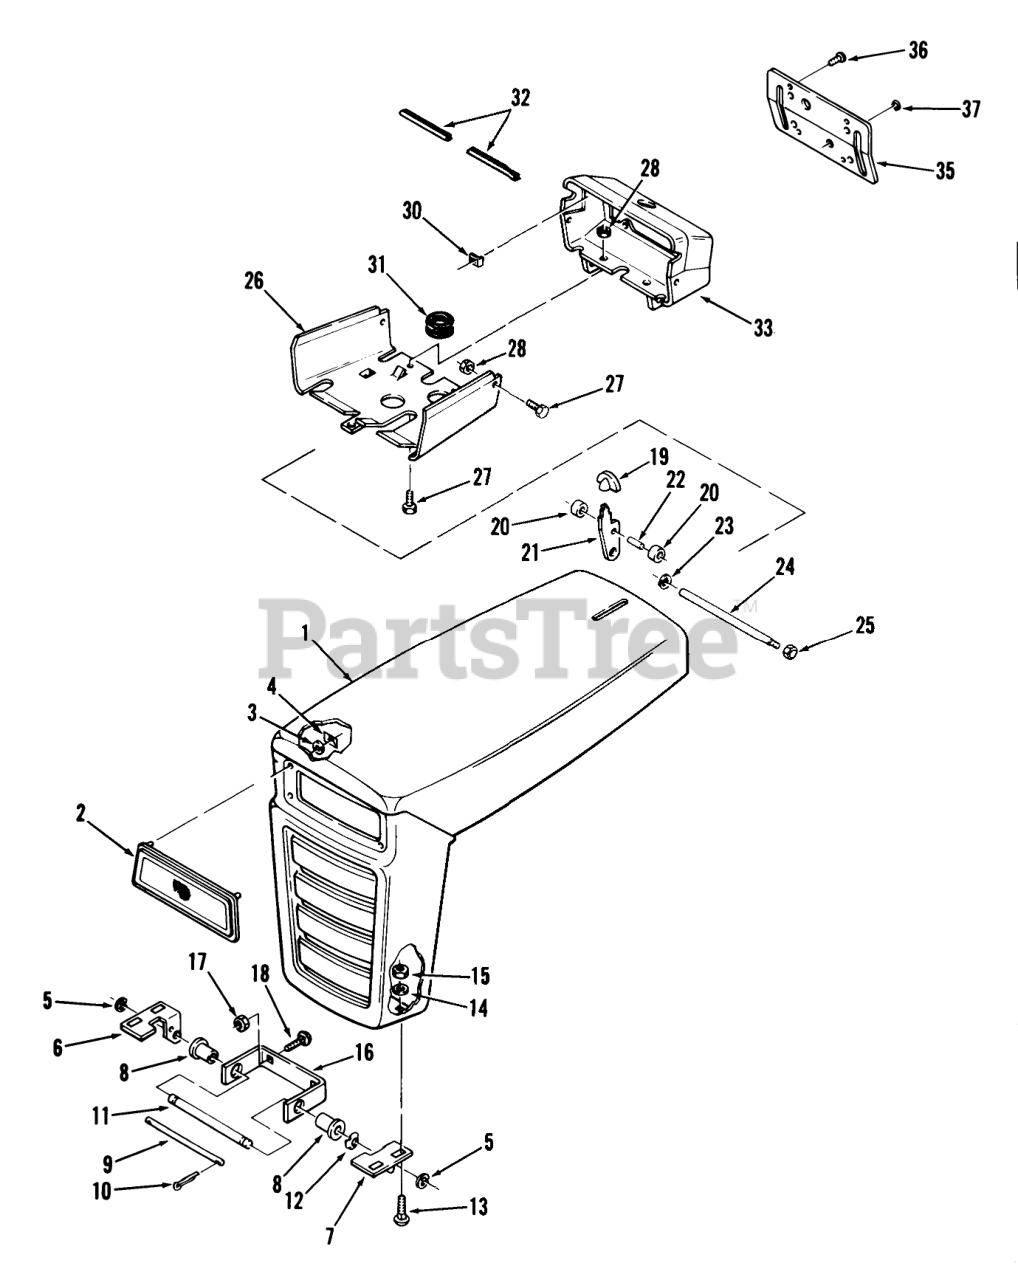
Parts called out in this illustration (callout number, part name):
1	Hood
2	ESCUTCHEON PLATE
3	WASHER
4	SPEED NUT
5	RING-RETAINING
6	BRKT-GRILL PIVOT RH
7	BRKT-GRILL PIVOT LH
8	BUSHING-NYLINER
9	ROD PIVOT STOP
10	Cotter Pin
11	Rod-Pivot
12	WASHER-SPRING
13	Bolt
14	WASHER 5/16 SAE
15	Nut
16	Bracket-Hood Pivot
17	Nut
18	Bolt-Carriage
19	KNOB
20	Roller
21	LEVER HOOD LATCH
22	SPIROL PIN
23	SPEED NUT
24	Rod Latch
26	Support-Tank
27	Screw
28	Nut
30	SPEED NUT
31	Grommet
32	EDGE TRIM 4IN OF 102896
33	Housing
35	Control Panel
36	SCREW BLACK
37	PLUG BUTTON
